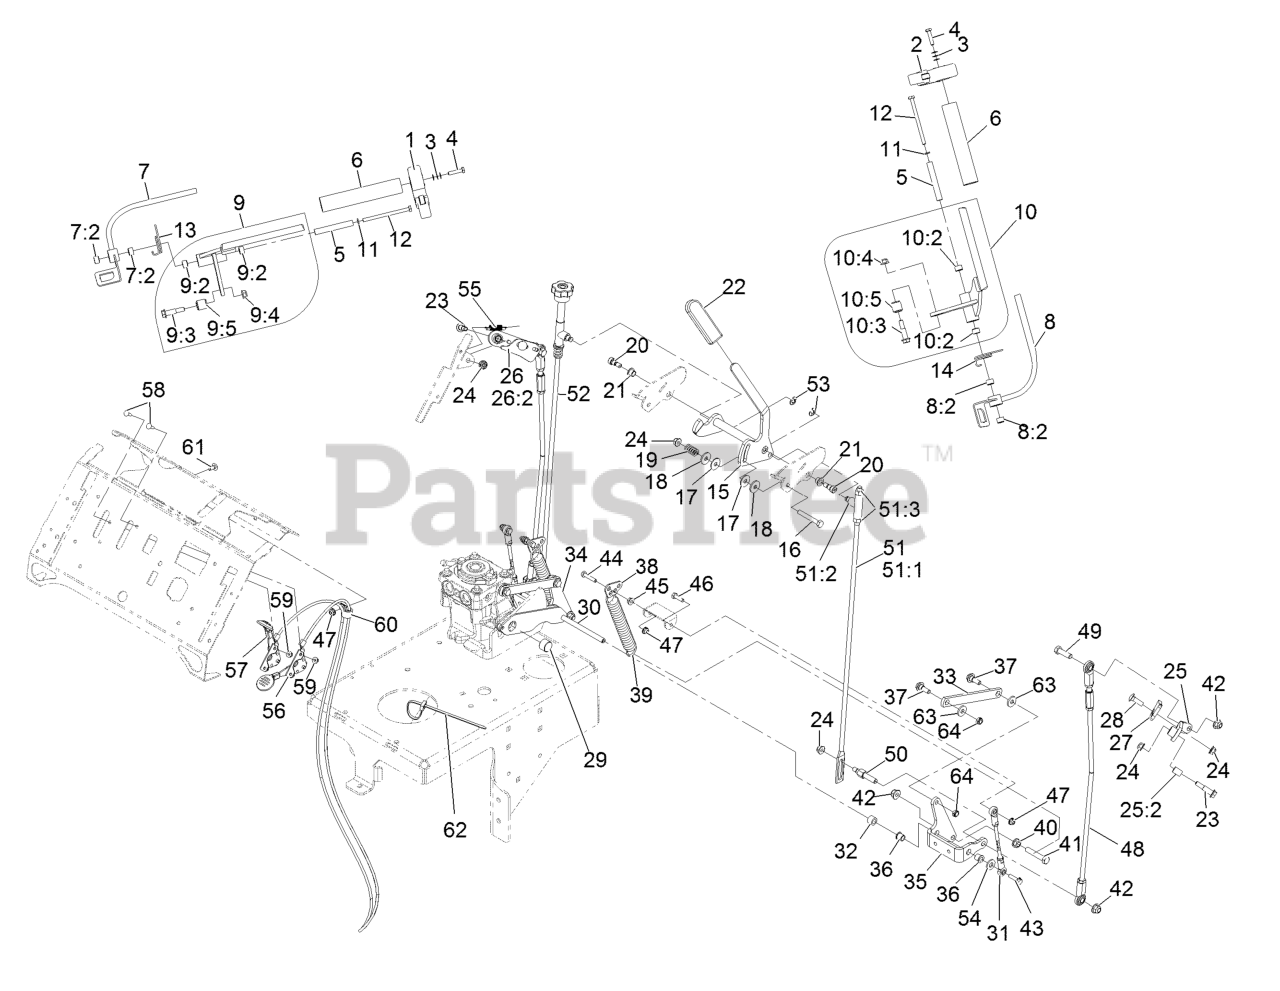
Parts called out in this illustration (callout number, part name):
1	ASM,LATCH RH THUMB
2	ASM,LATCH LH THUMB
3	WASHER-SPRING
4	SCREW-HH
6	GRIP-BAR, HANDLE
7	OPC-W/BUSHING, RH
7:2	BUSHING-SLEEVE
8	OPC-W/BUSHING, LH
8:2	BUSHING-SLEEVE
9	ASM, CONTROL-RH
9:2	BUSHING-SLEEVE
9:3	SCREW-SHOULDER
9:4	NUT-HF, NI
9:5	ASM, ROLLER
10	ASM, CONTROL
10:2	BUSHING-SLEEVE
10:3	SCREW-SHOULDER
10:4	NUT-HF, NI
10:5	ASM, ROLLER
11	SCREW-HH
12	SCREW-HH
13	SPRING, TORSION
14	SPRING, TORSION
15	SPEED CONTROL ASM
16	SCREW-HH
17	WASHER-FRICTION
18	WASHER-FRICTION
19	SPRING-COMPRESSION
20	SCREW-HSH
21	BUSHING
22	GRIP-HANDLE, STEERING
23	SCREW-SHOULDER
24	NUT-HF, NI
25	ARM ASM-LEFT
25:2	SLEEVE-BEARING
26	ARM ASM -RIGHT
26:2	SLEEVE-BEARING
28	BOLT-CARR
29	PIN-BELLCRANK LINK RETAIN
30	BELLCRANK LINK ASM
31	ASM, LINK
32	SPACER-WHEEL
33	LINK-BELLCRANK, PUMP
34	BELLCRANK-LOWER, RT
35	BELLCRANK-LOWER, LT
36	BEARING
37	SCREW-SHOULDER
38	LINK, ADJUSTABLE
39	SPRING-EXTENSION
40	NUT-HHF, WHIZ
41	SCREW-HH
42	NUT-HF, NI
43	SCREW-HHF
44	SCREW-HH
46	SCREW-HH
48	ASM, ROD
49	SCREW-HH
50	STUD-CONTROL, SPEED
51	ASM, ROD LEFT
51:1	ROD, LEFT
51:3	NUT-HJ
52	ASM, ROD RIGHT
53	RING-RETAINING
54	WASHER-FRICTION
55	SPRING-EXTENSION
56	CONTROL-THROTTLE
57	CONTROL-CHOKE
58	BOLT-CARR
59	NUT-LOCK, FLANGE
60	CLAMP-CABLE
61	SCREW-CARR
62	TIE-CABLE
63	WASHER-FLAT
64	NUT-LOCK, NI
